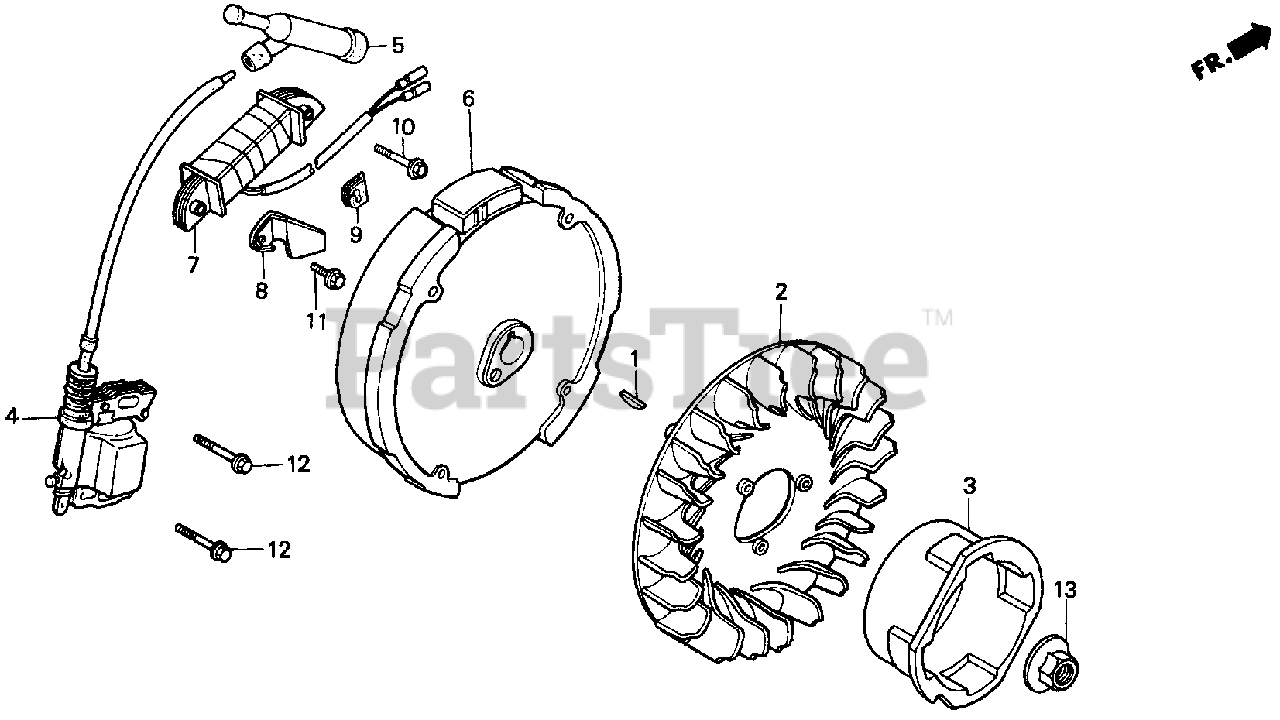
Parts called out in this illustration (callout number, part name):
1	KEY, SPECIAL WOODRUFF (25X18)
2	FAN, COOLING
3	PULLEY, STARTER
4	COIL ASSY., IGNITION
5	CAP ASSY., NOISE SUPPRESSOR (NICHIWA Y-EZ RTFM256)
6	FLYWHEEL (LAMP)
7	COIL ASSY., BACK-UP
8	CLAMP, WIRE
9	GROMMET, WIRE
10	BOLT, FLANGE (6X28)
11	BOLT, FLANGE (5X10)
12	BOLT, FLANGE (6X25)
13	NUT, SPECIAL (14MM)
